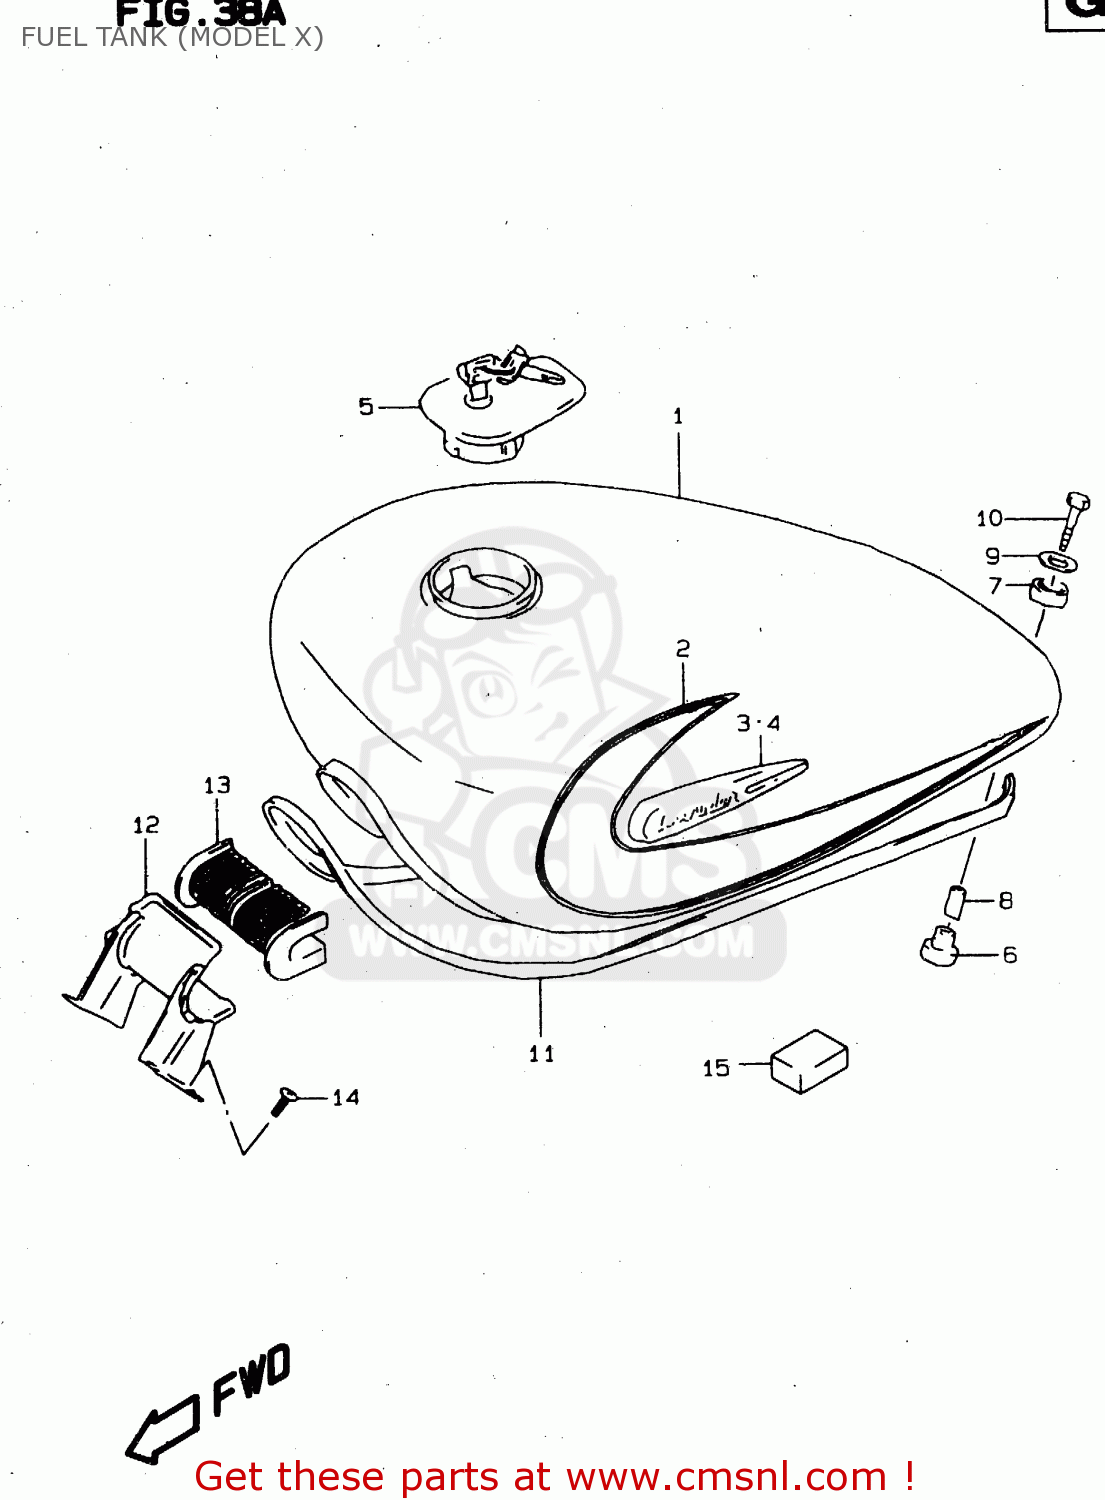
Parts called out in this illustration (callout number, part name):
1	TANK ASSY,FUEL
2	TAPE SET,FUEL TANK
3	EMBLEM,FUEL TANK,R
4	EMBLEM,FUEL TANK,L
5	CAP SET,FUEL TANK
6	CUSHION
7	CUSHION
8	SPACER(6.5X9X21.5)
9	WASHER(6.5X24X1.6)
10	SCREW
11	MOLDING
12	BRACKET,FUEL TANK FR
13	CUSHION,FUEL TANK FR
14	SCREW
15	CUSHION
